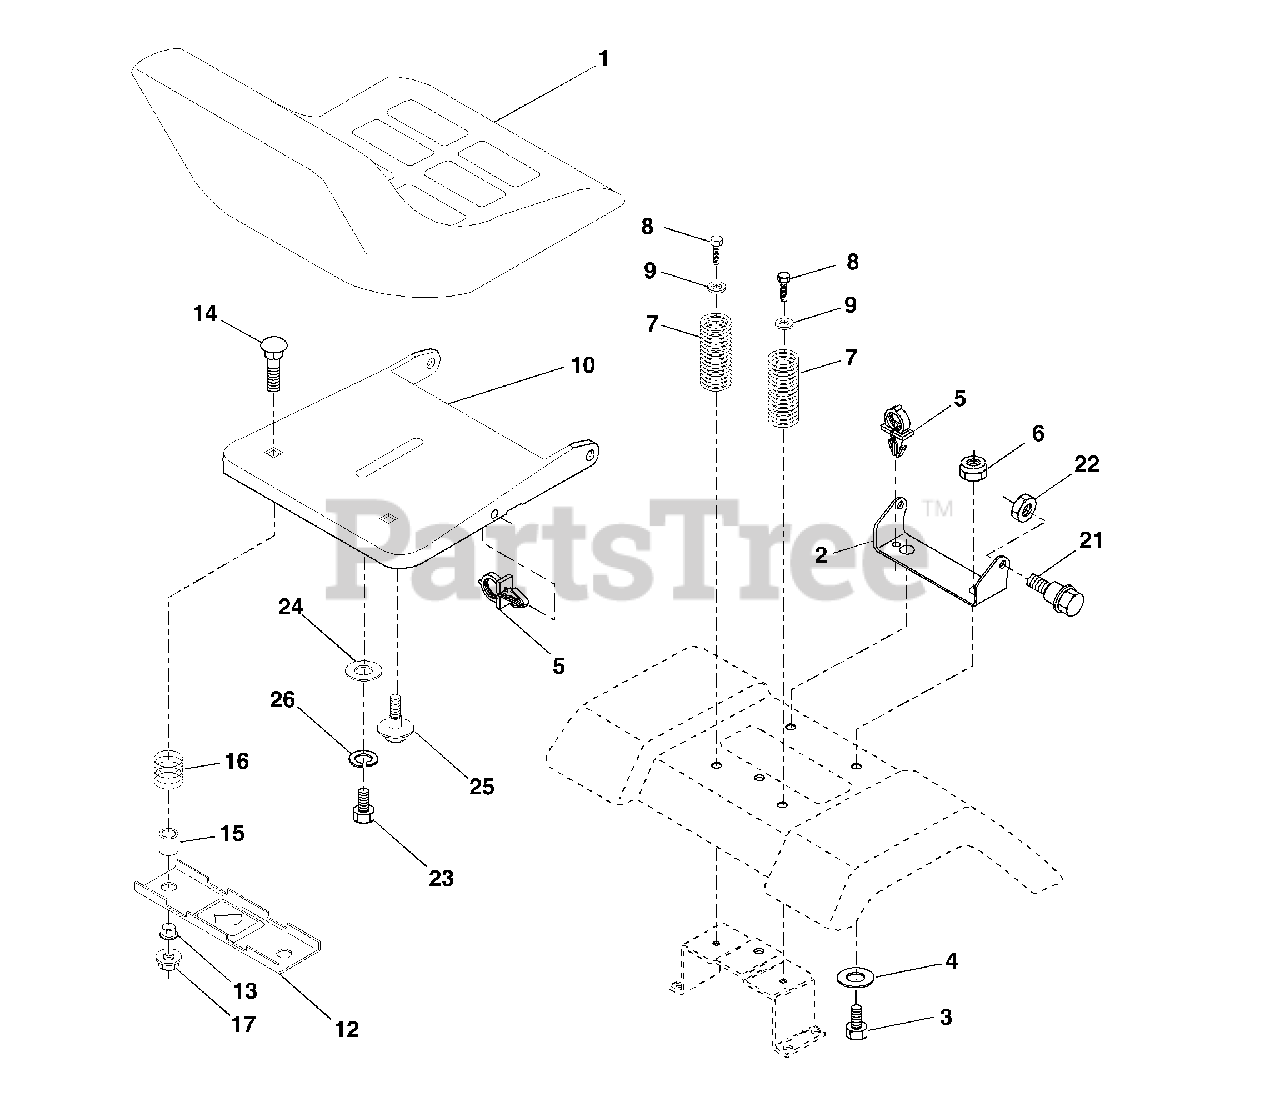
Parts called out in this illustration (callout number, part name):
1	Seat
2	Bracket Pnt Pivot Seat (blk )
3	Bolt
4	Washer 13/32 x 1 x 10 Ga
5	Clip Push-In Hinged
6	Nut
7	Spring Seat Cprsn 2 250 Blk Zi
8	Screw 3/8-16 x 1.5
9	Washer 13/32 x 1 x 14 Ga
10	Pan Pnt Seat (blk )
12	Bracket Pnt Mounting Switch
13	Bushing Snap Blk Nyl 50 Id
14	Bolt Rdhd Sht Nk 1/4-20 x 1-1/2
15	Spacer Split 28 x 96 Yel Zinc
16	Spring Cprsn 1 27 Blk Pnt
17	Nut Lock 1/4 Lge Flg Gr 5 Zinc
21	Bolt Shoulder 5/16-18 Unc Blkz-2A
22	Nut
23	Bolt Hex Black
24	Washer 17/32 x 1-3/16 x 12 Ga
25	Bolt Shoulder 5/16-18 x 62
26	Lockwasher
